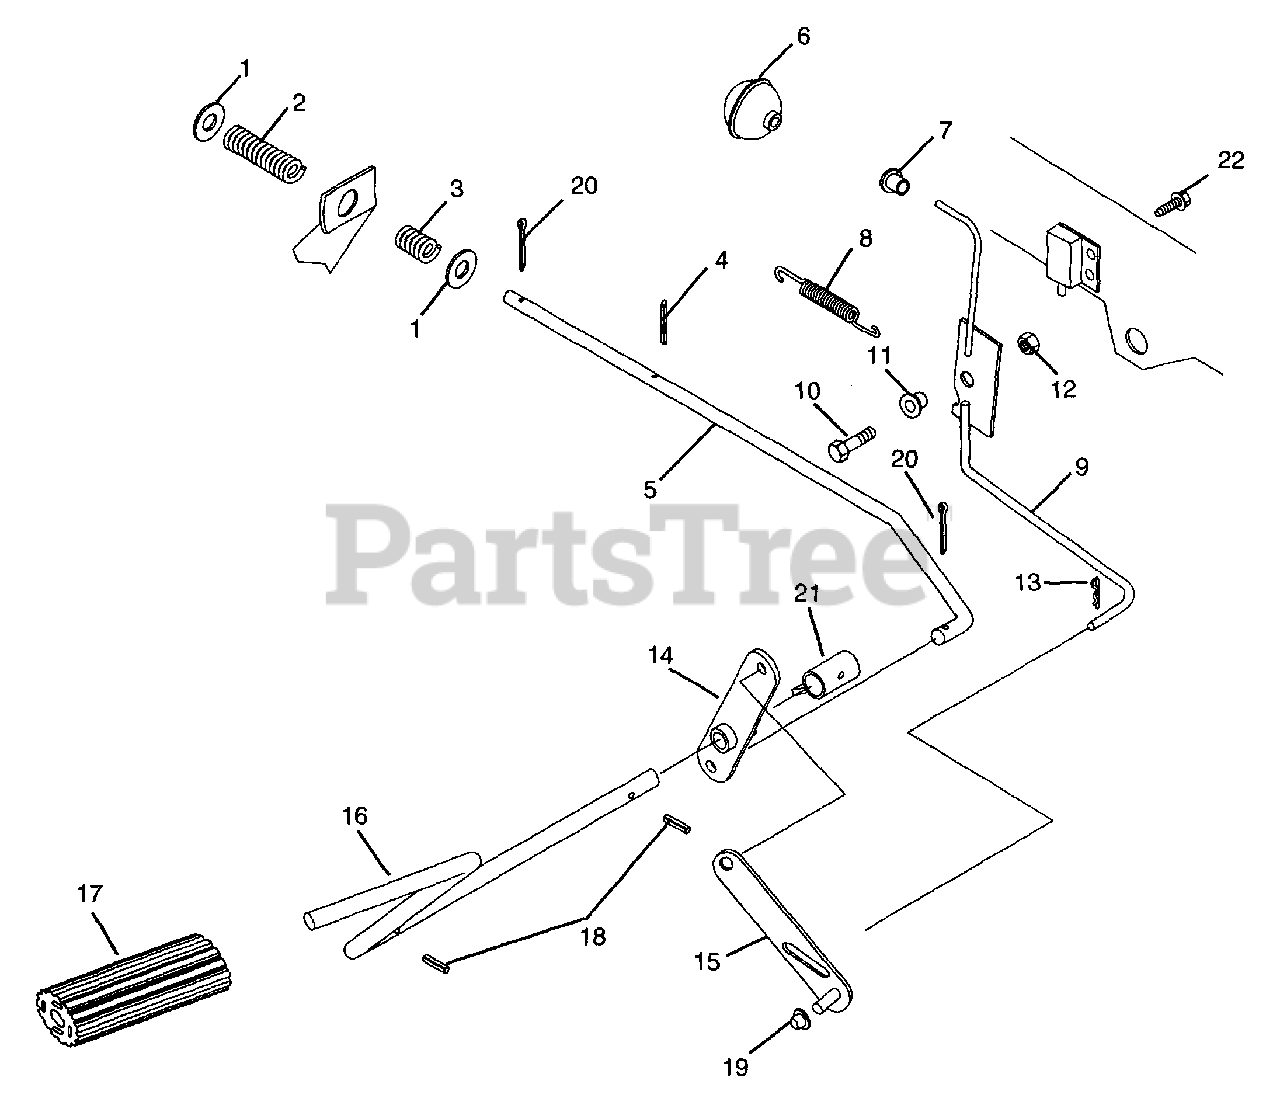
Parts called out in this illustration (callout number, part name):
1	WSHR-FL-STL.406X.812X.065PL
2	SG-COMP .048X.59X2.06 WLD9
3	SG-COMP .125X.78X1.00 YWZ
4	PIN-ROLL .125X.75
5	BRAKE ROD
6	PUSH/PULL CONTROL KNOB
7	SNAP BUSHING-.437
8	SG-TENS .051X.44X4.38 WLD 7.5
9	PARKING BRAKE LEVER
10	BLT-HEX .31-18X.75 PL GR5
11	BSHG, FLG .325X.499X.26X.88
12	NUT-LK .312-18 GR A PL
13	PIN-HAIR INT .08X.18X1.18
14	ARM & HUB - HYDRO
15	PIVOT PLATE
17	COVER- PEDAL
18	PIN-GRV .188X1.25 TP A
19	NUT-PUSH .312 DIA. PAL
20	PIN-COTR .09X.75 PL
21	BRAKE SWITCH LEVER
22	SCR-TAP 12-24X.50 HWH PL TR
